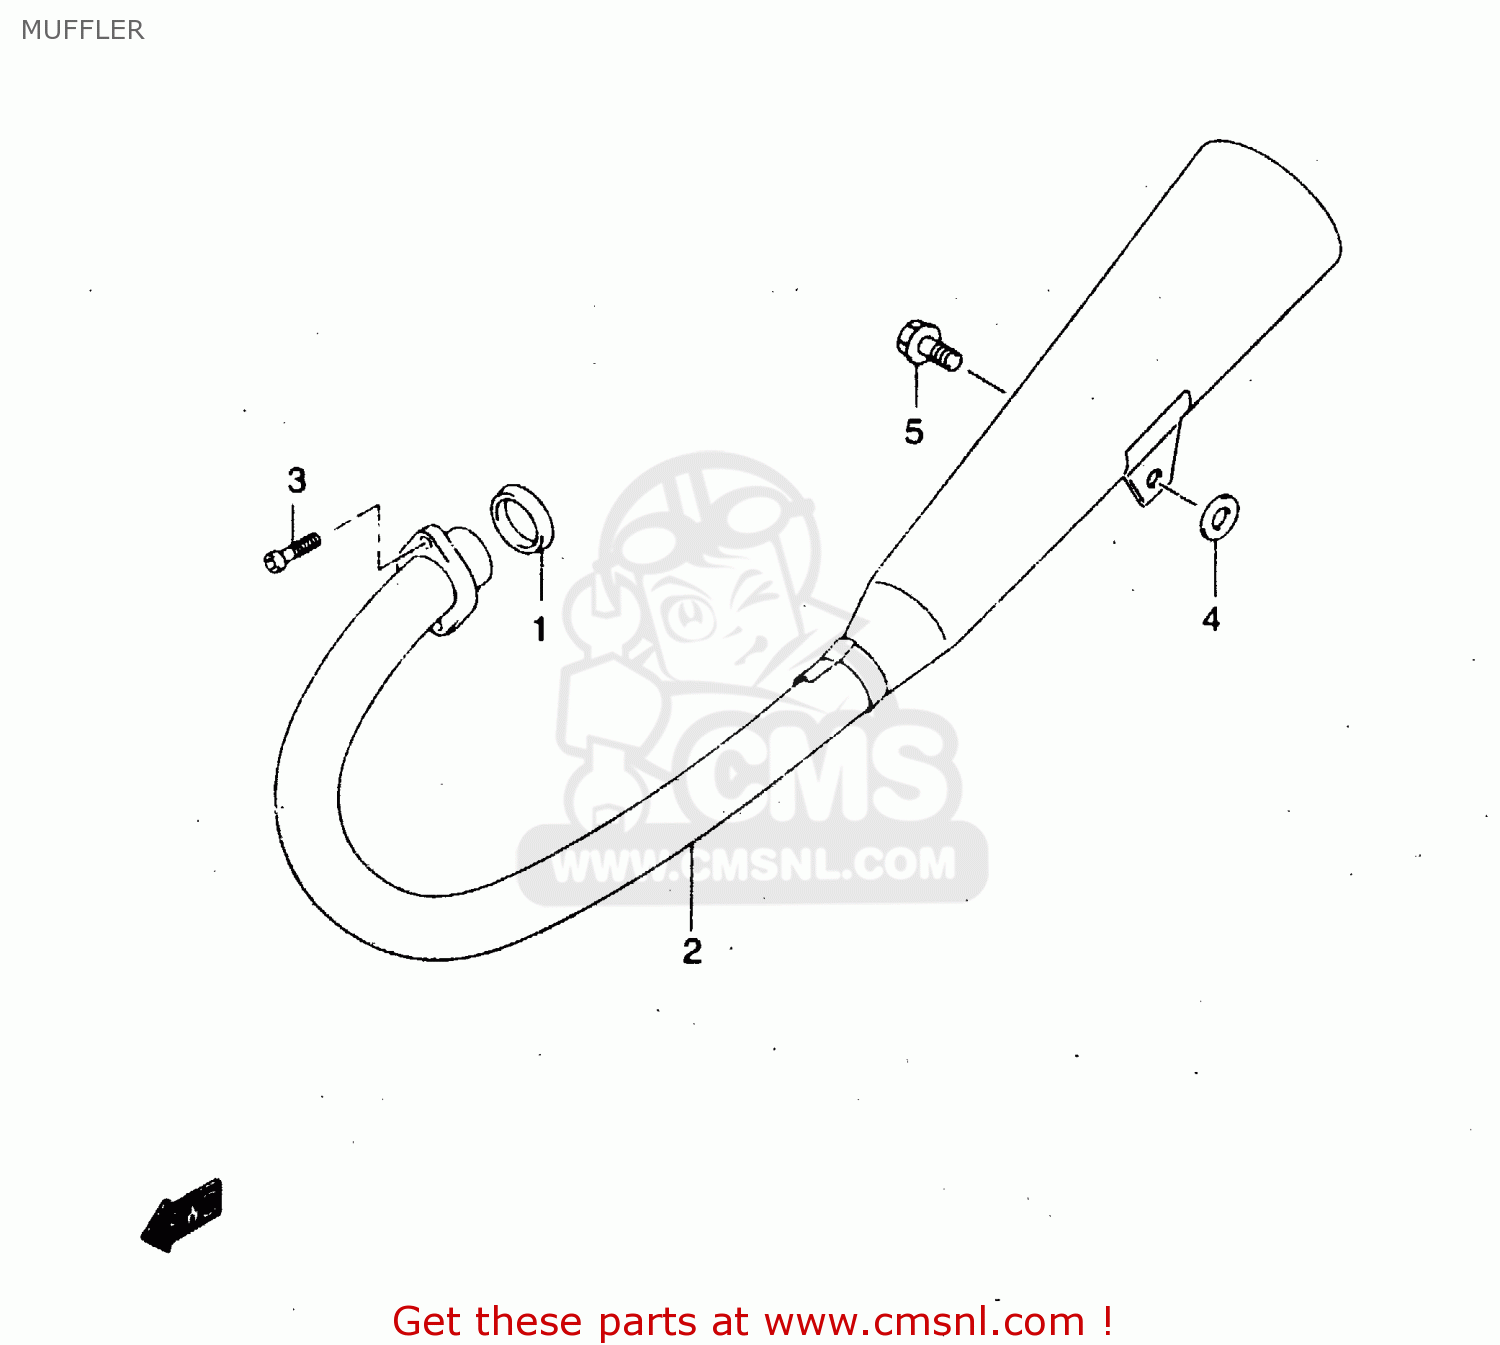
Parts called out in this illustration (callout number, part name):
1	GASKET,EXHAUST (NAS)
2	MUFFLER
3	BOLT
4	WASHER
5	BOLT
